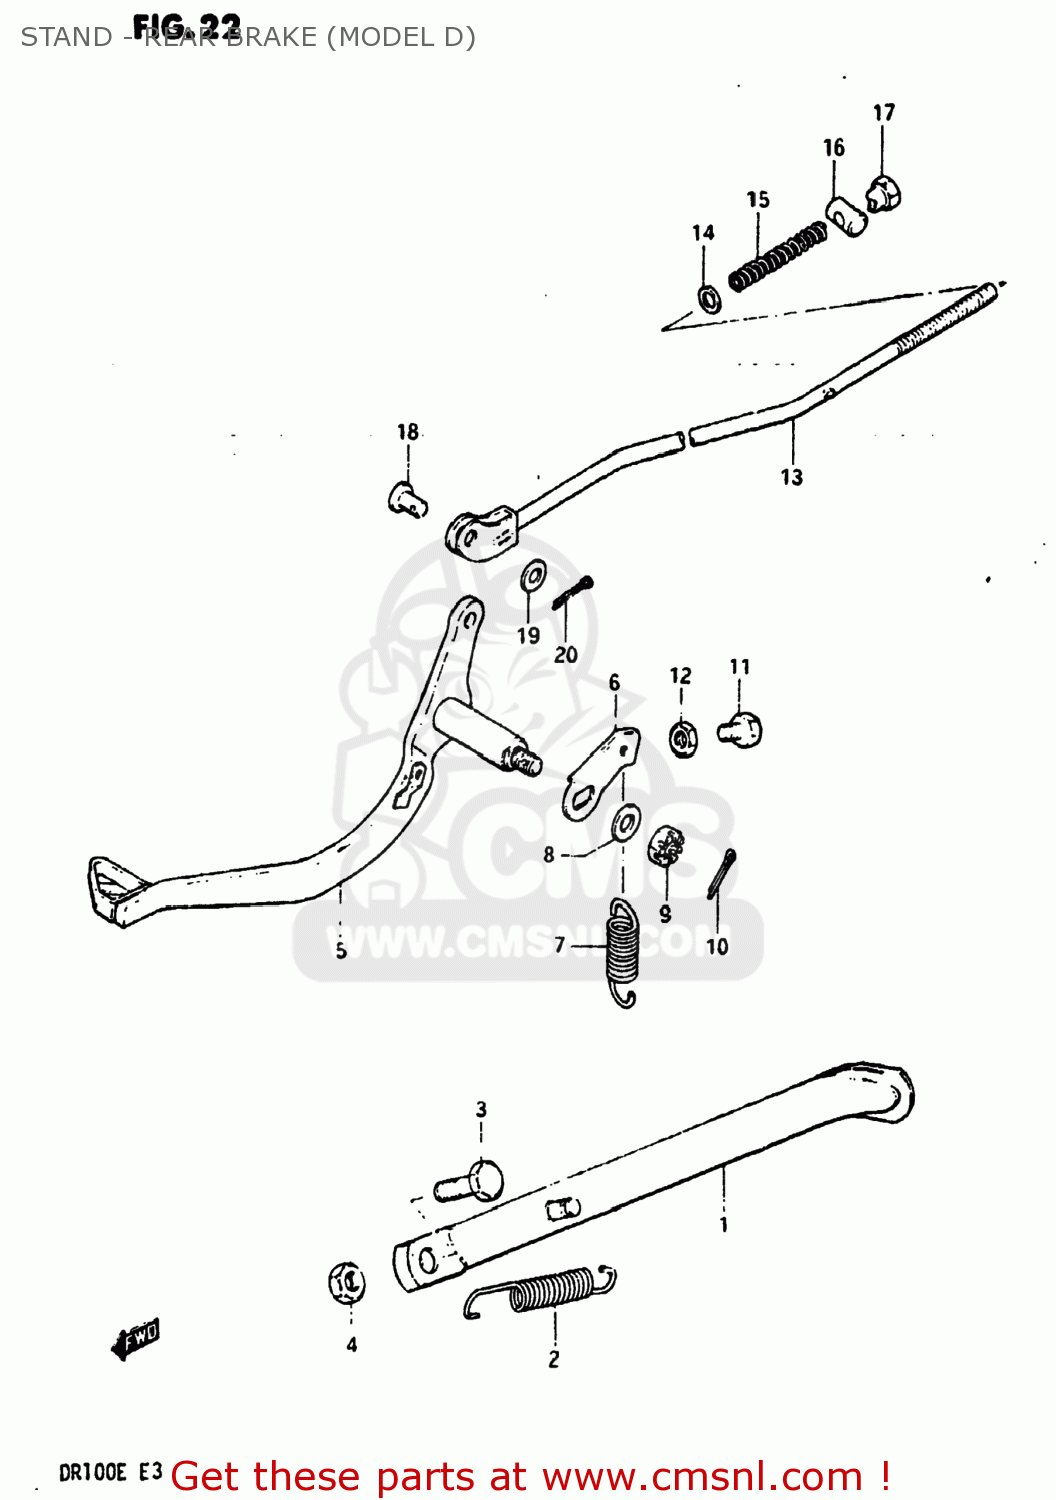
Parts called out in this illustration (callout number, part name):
1	STAND,SIDE
2	SPRING
3	BOLT(10X30)
4	NUT
5	PEDAL,BRAKE
6	ARM,BRAKE RETURN SPRING
7	SPRING
8	WASHER
9	NUT 8MM
10	PIN 20X20
12	NUT
13	ROD ASSEMBLY,REAR BRAKE
14	WASHER
15	SPRING
16	PIN(11X18)
17	NUT (6MM)
18	PIN
19	WASHER
20	PIN 20X20
